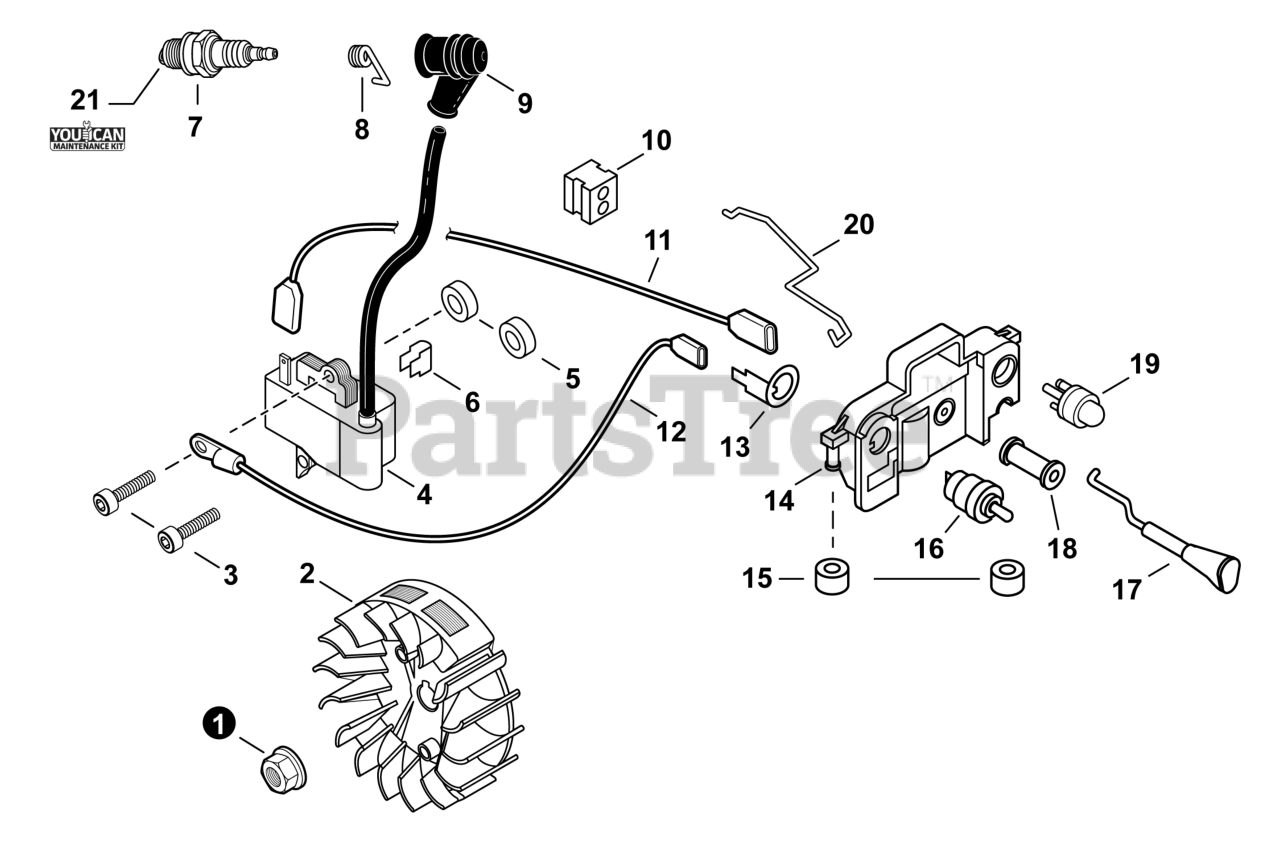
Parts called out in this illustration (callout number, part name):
1	NUT, FLANGE M8
2	FLYWHEEL
3	BOLT 5×20
4	COIL, IGNITION
5	WASHER 5.2×12×3
7	SPARK PLUG - BPM8Y
8	TERMINAL, SPARK PLUG
9	CAP, SPARK PLUG
10	GROMMET, LEAD
11	LEAD - IGNITION L= 172
12	LEAD - GROUND L= 140
13	TERMINAL, GROUND
14	BRACKET, SWITCH
16	SWITCH, ON-OFF
17	KNOB, CHOKE
18	GROMMET, CHOKE
19	BULB, PURGE
20	ROD, THROTTLE
21	TUNE-UP KIT - YOUCANT
